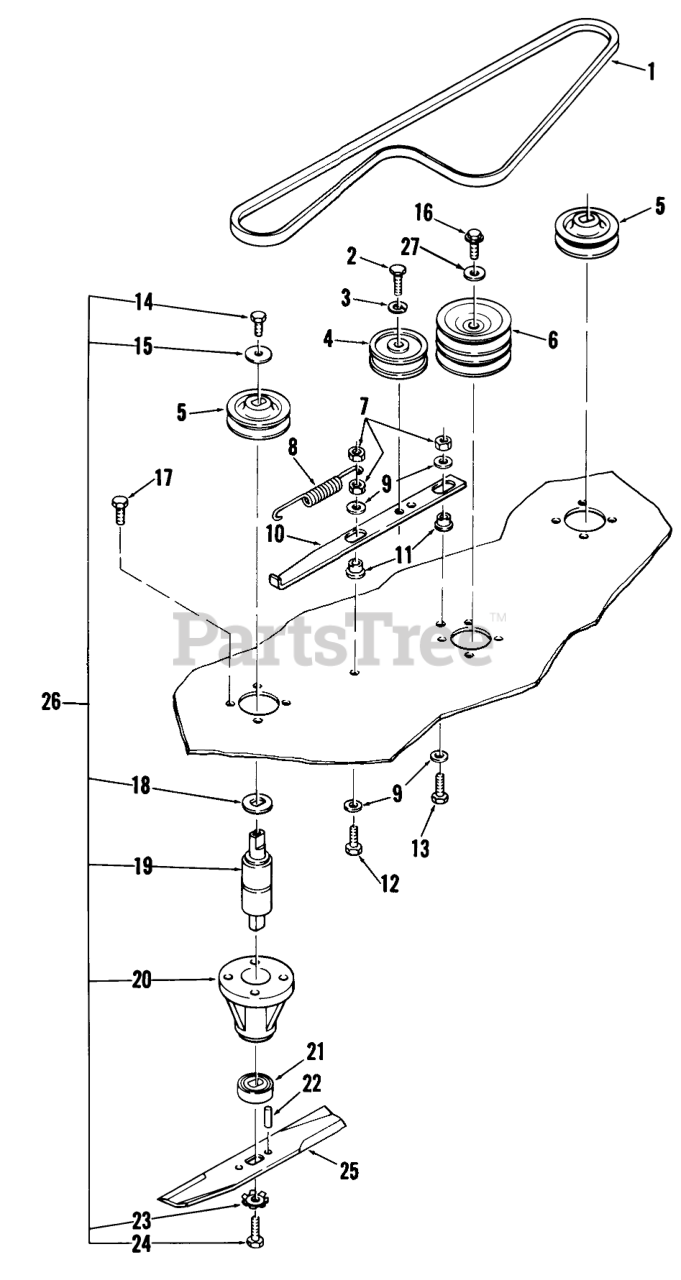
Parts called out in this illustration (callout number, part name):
1	V-BELT
2	BOLT HEX SPECIAL
3	LOCKWASHER
4	Idler Pulley
5	PULLEY-MOWER DRIVE
6	PULLEY-36IN MOWER
7	Nut
8	SPRING-EXTENSION
9	WASHER
10	BAR-IDLER SUPPORT
11	Bushing/Spacer
12	Bolt
13	Bolt
14	Bolt
15	WASHER
16	Bolt-Lock 3/8-16 x 7/8
17	Bolt
18	WASHER-DOUBLE D
19	BEARING
20	HOUSING-BEARING B
21	Cup-Spindle
22	SPIROL ROLL PIN
23	WASHER
24	Bolt
25	BLADE KIT 36 LF REAR
25	BLADE KIT
26	S/A SPINDLE ASSY
27	Washer
